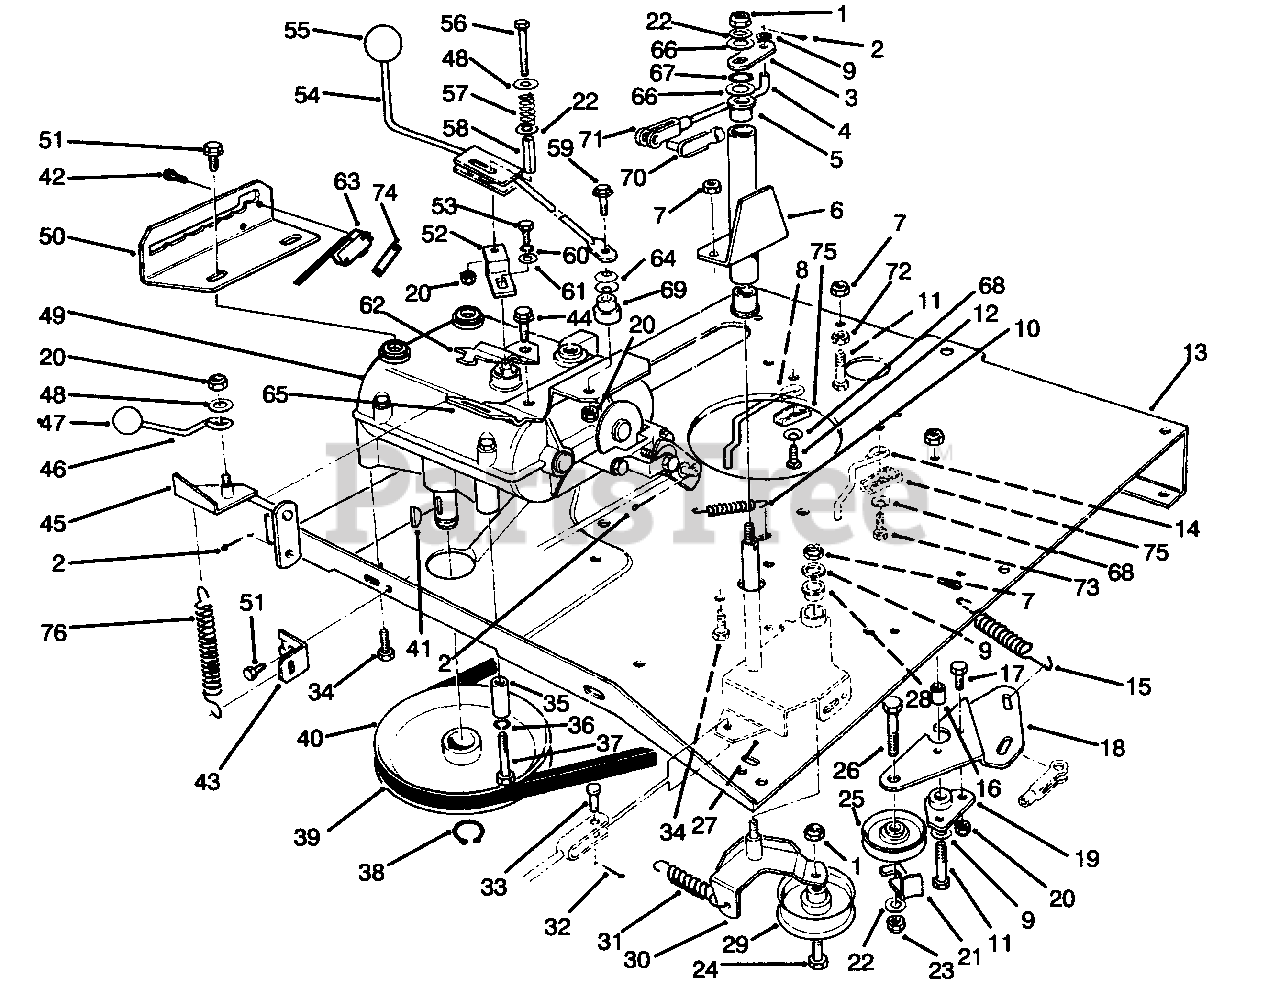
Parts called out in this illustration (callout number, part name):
1	Nut-Lock
2	Pin-Cotter
3	Flat-Deck Engage
4	Link-Deck Engage
5	Bushing
6	Tube W.A.-Pivot (Incl. Ref. #5)
7	Nut-Lock
8	Guide R.H.-Belt, Engine
9	Washer-Flat
10	Spring-Return, Brake
11	Screw-Cap Hex. Hd.
12	Bolt-Carriage
13	Plate-Engine
14	Guide L.H.-Belt, Engine
15	Spring-Traction
16	Spacer-Pivot
17	Screw-Cap Hex. Hd.
18	Plate-Mount, Idler
19	Mount-Pivot
20	Nut-Lock
21	Retainer-Belt
22	Washer-Flat
23	Nut-Lock
24	Screw-Cap Hex. Hd.
25	Pulley-Idler, Traction
26	Screw-Cap Hex. Hd.
27	Bracket-Arm, Idler (Incl. Ref. #28)
29	Pulley-Idler, Deck
30	Idler-Plate, Mount
32	Pin-Cotter
33	Pin-Clevis
34	Screw-Cap Hex. Hd.
35	Guide-Belt
36	Washer-Lock
37	Screw-Cap Hex. Hd.
38	Ring-Retaining
39	Belt-Traction
40	Pulley-Transmission
42	Screw-Tapping
43	Bracket-Mount, Spring
44	Screw-Hex. Hd. Tapping
45	Lever W.A.-Deck Engage
46	Handle-Deck Engage
48	Washer-Fender
49	Transmission
50	Gate-Shift
51	Screw-Wash. Hd., Tap.
52	Lever-Shift
53	Screw-Cap Hex. Hd.
54	Lever W.A.-Shift
56	Screw-Cap Hex. Hd.
59	Screw-Cap Hex. Hd.
60	Washer-Lock
61	Washer-Flat
62	Bracket-Engage, Deck
63	Switch-Micro
64	Washer-Belleville
65	Bracket-Mount, Shifter
66	Washer-Flat
67	Ring-Retaining
68	Washer-Belleville
69	Spacer-Pivot
70	Assembly-Pin, Clevis
72	Nut-Jam
73	Screw-Thread Forming
74	Nut-Double
75	Anchor-Guide, Belt
